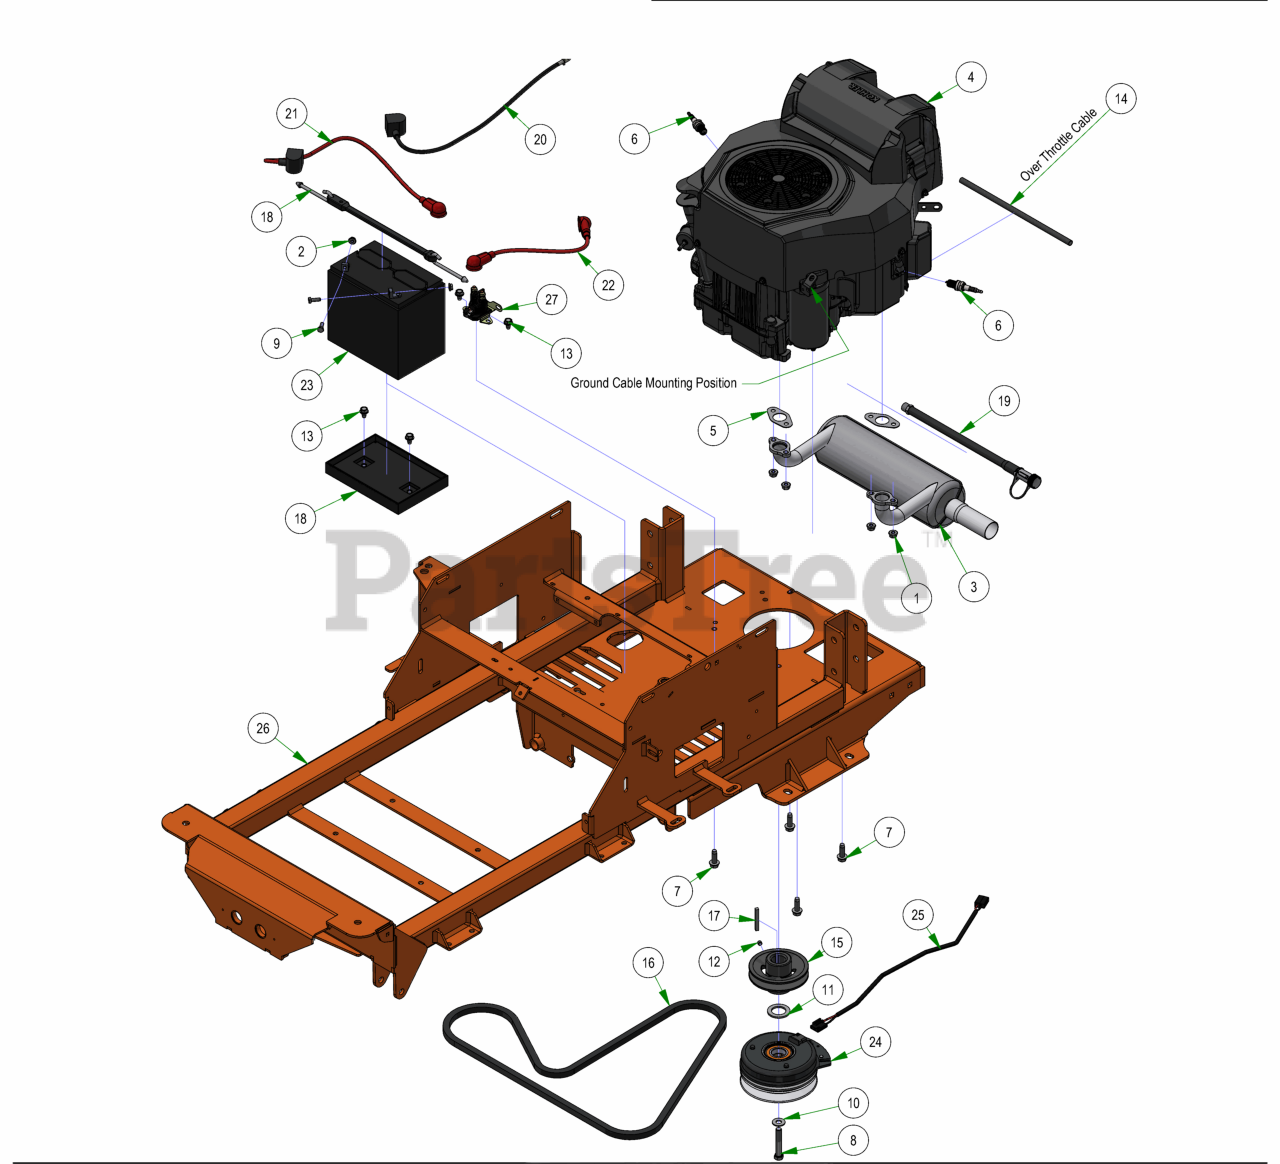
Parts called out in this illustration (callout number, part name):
1	M8 Nut Connects the 015-1012-00 and the 015-8240-00
2	1 4-20 HEX SERRATED FLANGE NUT HARD ZINC
3	Kohler Muffler
4	Kohler-2014 CZT Outlaw 747cc
5	Exhaust Gasket
6	Spark Plug
7	3 8-16 X 1-1 8 HEX WASHER UNSLOT SERRATED (TRI-LOB) TRS ZINC YELLOW
8	7 16-20 X 2.5" HEX Bolt GR.8 W Patch
9	1 4-20 X 3 4 HEX CAP SCREW (GR.5) ZINC
10	3 8 FLAT WASHER USS (1" OD) ZINC
11	1.140 ID X 1.750 OD X .132 THICK FLAT WASHER PLAIN
12	5 16-24 X 1 4 SOCKET SET SCREW (CUP PT) PLAIN
13	5 16-18 X 1 2 HWH unslot (F) tcs zinc
14	Braided Heat Shielding, 12"
15	4 3 4 Motor Pulley
16	75.8" Pump Belt
17	1 4 X 2 SQ MACHINERY KEY 1018 STL PLAIN
18	2023 Battery Hold Down Assembly
19	Kohler Oil Drain
20	24 inch Black Cable – MZ ZT
21	24" Red Battery Cable
22	12" Red Battery Cable
23	SP-35 Battery
24	120 Ft Lb. Clutch - 1 1 8" Shaft
25	Clutch Pigtail
26	2025 Maverick Frame
